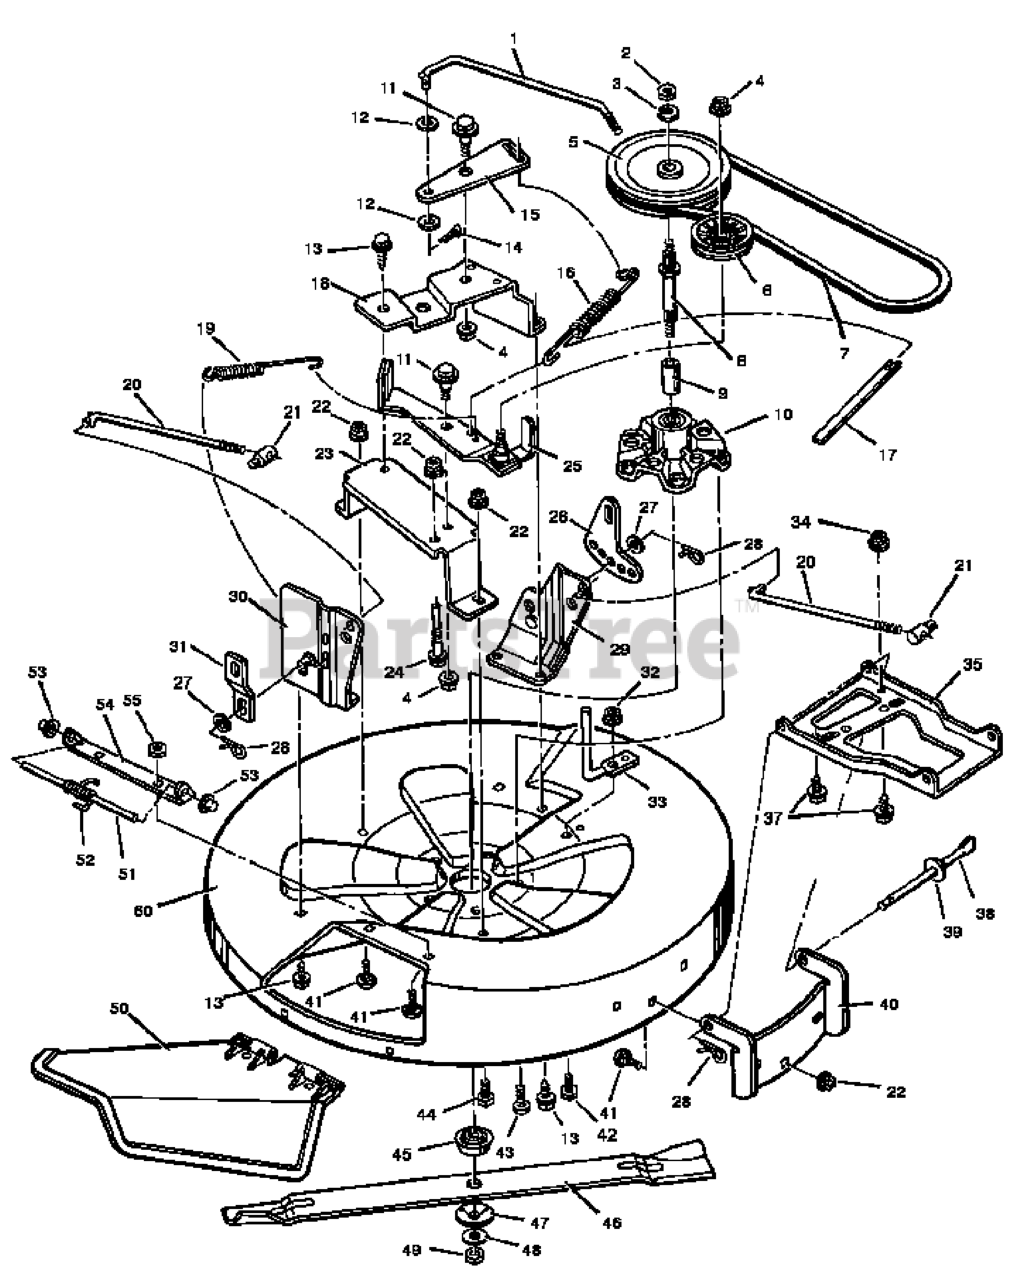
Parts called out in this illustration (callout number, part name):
1	Rod, PTO
2	Locknut
3	Lockwasher
4	Locknut, Flange
5	Pulley, Splined
6	Pulley, Idler
7	Belt, Mower Drive
8	Mandrel
10	Housing, Mandrel
11	Bolt, Shoulder
14	Pin, Cotter
15	Bracket, Pivot
16	Spring, Extension
17	Indicator, Plastic
18	Support, Pivot Bracket
19	Spring, Extension
20	Rod, Adjusting
21	Nut, Adjustable
22	Nut, Flange
23	Support, Idler Arm
24	Guide, Belt
25	Arm Assembly, Idler
26	Plate, Adjusting
28	Pin, Hair
29	Bracket Assembly, Left Lifter
30	Bracket Assembly, Right Lifter
32	Nut, Flange
33	Guide, Belt
34	Nut, Hex
35	Hanger, Front
38	Rod, Hanger
40	Bracket, Front Hanger
41	Bolt, Carriage
42	Bolt
44	Bolt
45	Adapter, Blade
47	Washer, Belleville
49	Nut, Hex
50	Deflector, Chute
51	Rod, Deflector
52	Spring - Torsional
53	Cap, Push On
54	Hinge, Deflector
55	Locknut
57	Bolt, Carriage
58	Wingnut
